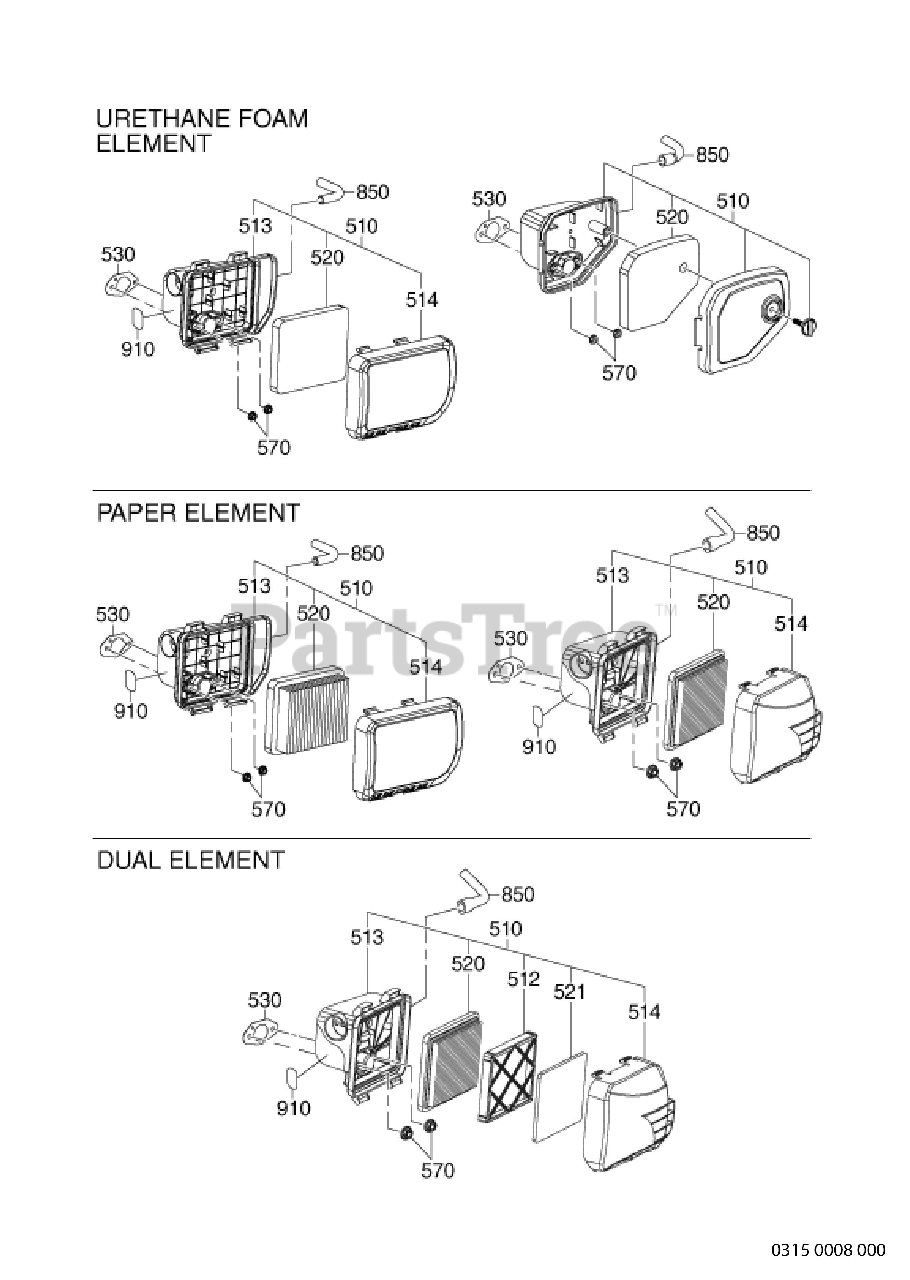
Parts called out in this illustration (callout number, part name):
513	AIR CLEANER BASE
514	AIR CLEANER COVER
520	AIR CLEANER ELEMENT - PAPER
530	AIR CLEANER GASKET
